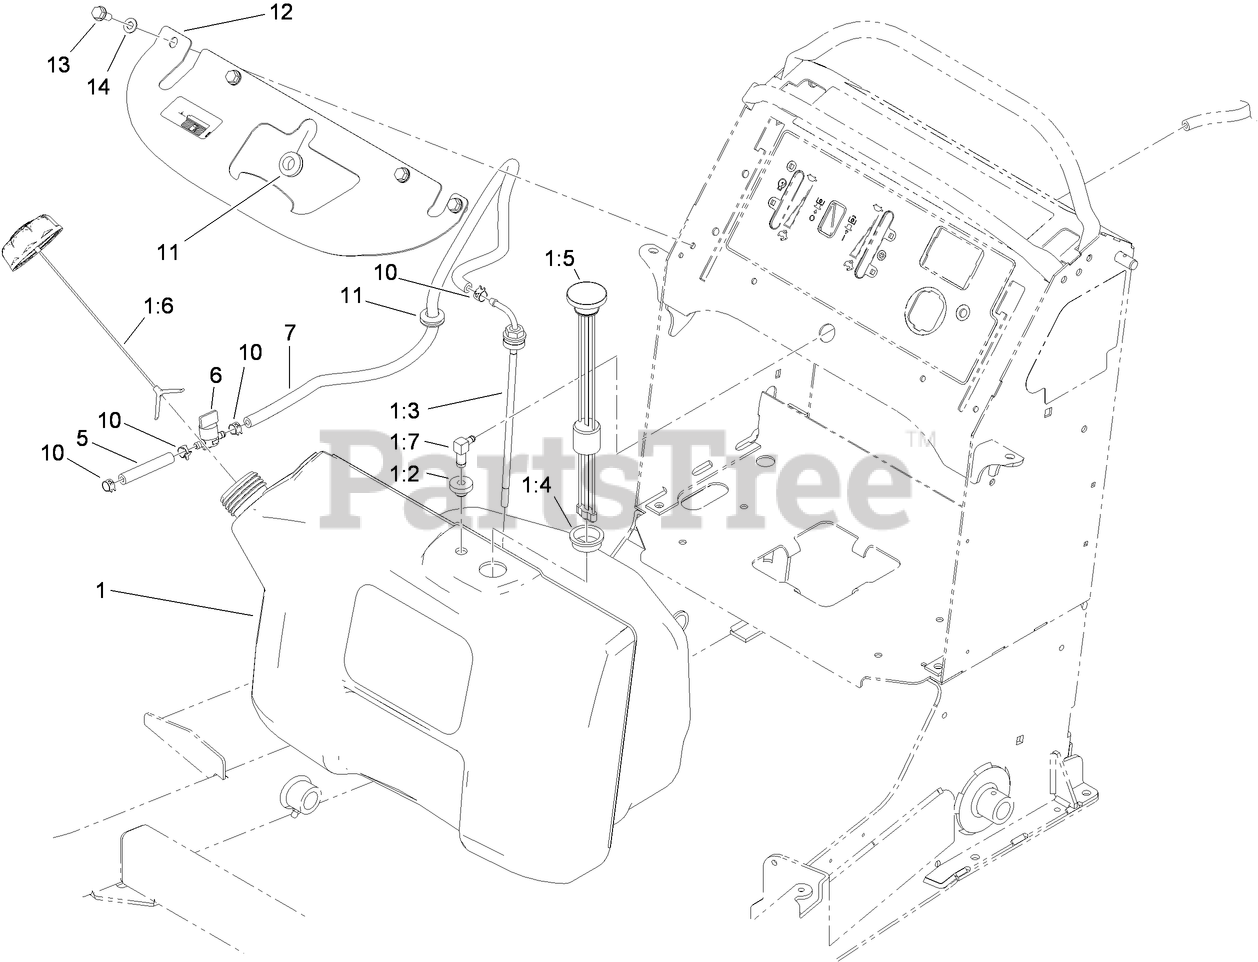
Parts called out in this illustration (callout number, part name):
1	TANK ASM
1:2	BUSHING
1:3	FITTING-FUEL, BULKHEAD
1:4	GROMMET
1:5	GUAGE-FUEL
1:6	CAP-FUEL, RATCHETING
1:7	ELBOW-90 DEG
5	HOSE-FUEL
6	VALVE-FUEL
7	HOSE-FUEL
10	CLAMP-HOSE
11	GROMMET
12	BRACKET-TANK
13	SCREW-HWHTF
14	WASHER-FLAT
